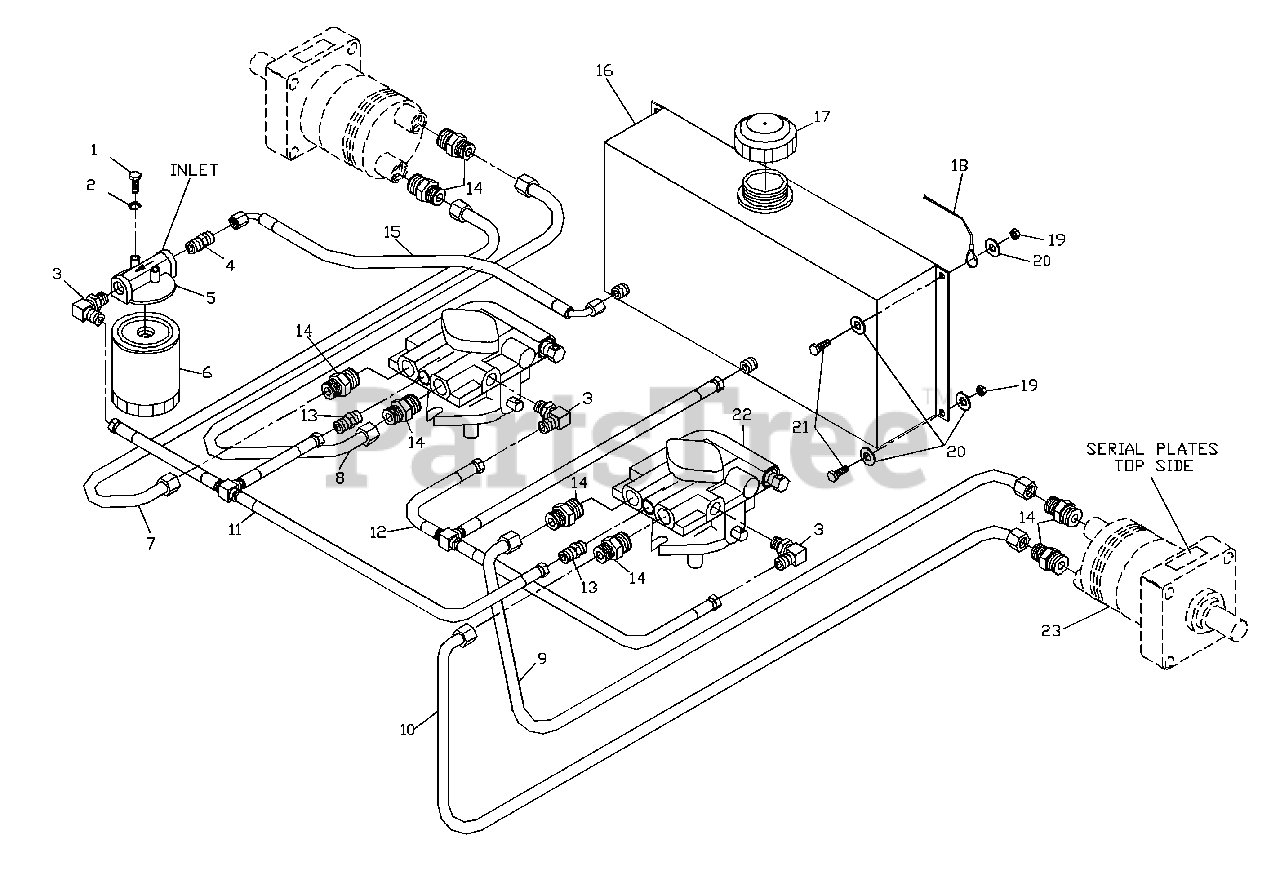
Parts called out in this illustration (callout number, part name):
1	HCS 1/4C X 5/8
2	1/4" LOCKWASHER
3	F6801-6-6-0 90 DEG. ELBOW
4	F6400-6-6-0 STRAIGHT FITTING
5	FILTER HEAD
7	RIGHT OUTSIDE TUBE
8	RIGHT INSIDE TUBE
9	LEFT INSIDE TUBE
10	LEFT OUTSIDE TUBE
11	SUCTION TEE ASSEMBLY
12	RETURN TEE ASSEMBLY
13	F6400-6-4-0 STRAIGHT FITTING
14	F6400-8-8-0 STRAIGHT FITTING
16	TANK, HYDRAULIC
17	HYDRAULIC CAP
18	SEAT LANYARD
19	NUT 1/4C CENTERLOCK
20	WASHER 1/4 FLAT
21	HCS 1/4C X 1
23	WHEEL MOTOR
